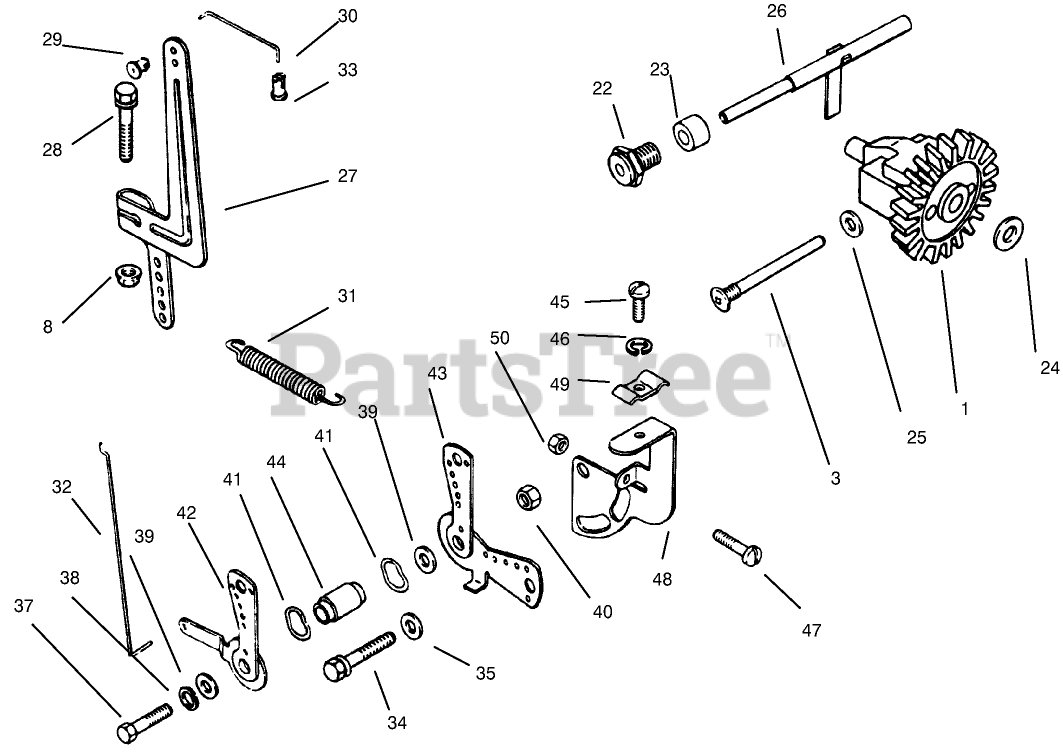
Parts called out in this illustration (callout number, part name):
1	Kit, Governor Gear
3	Pin-GovemorStop
8	Palnut
22	Bushing
23	Spacer
24	Washer
25	Washer
26	Kit-Governor Shaft
27	Lever-Governor
28	Screw
29	Bushing
30	Linkage
31	Spring
32	Linkage-Choke
33	Bushing
34	Screw
35	Washer
37	Screw
38	Washer
39	Washer
40	Nut
41	Washer
42	Lever-Choke Control
43	Lever-Throttle Control
44	Spacer
45	Screw
46	Washer
47	Screw
48	Bracket-Clutch Contro;
49	Clamp
50	Nut
